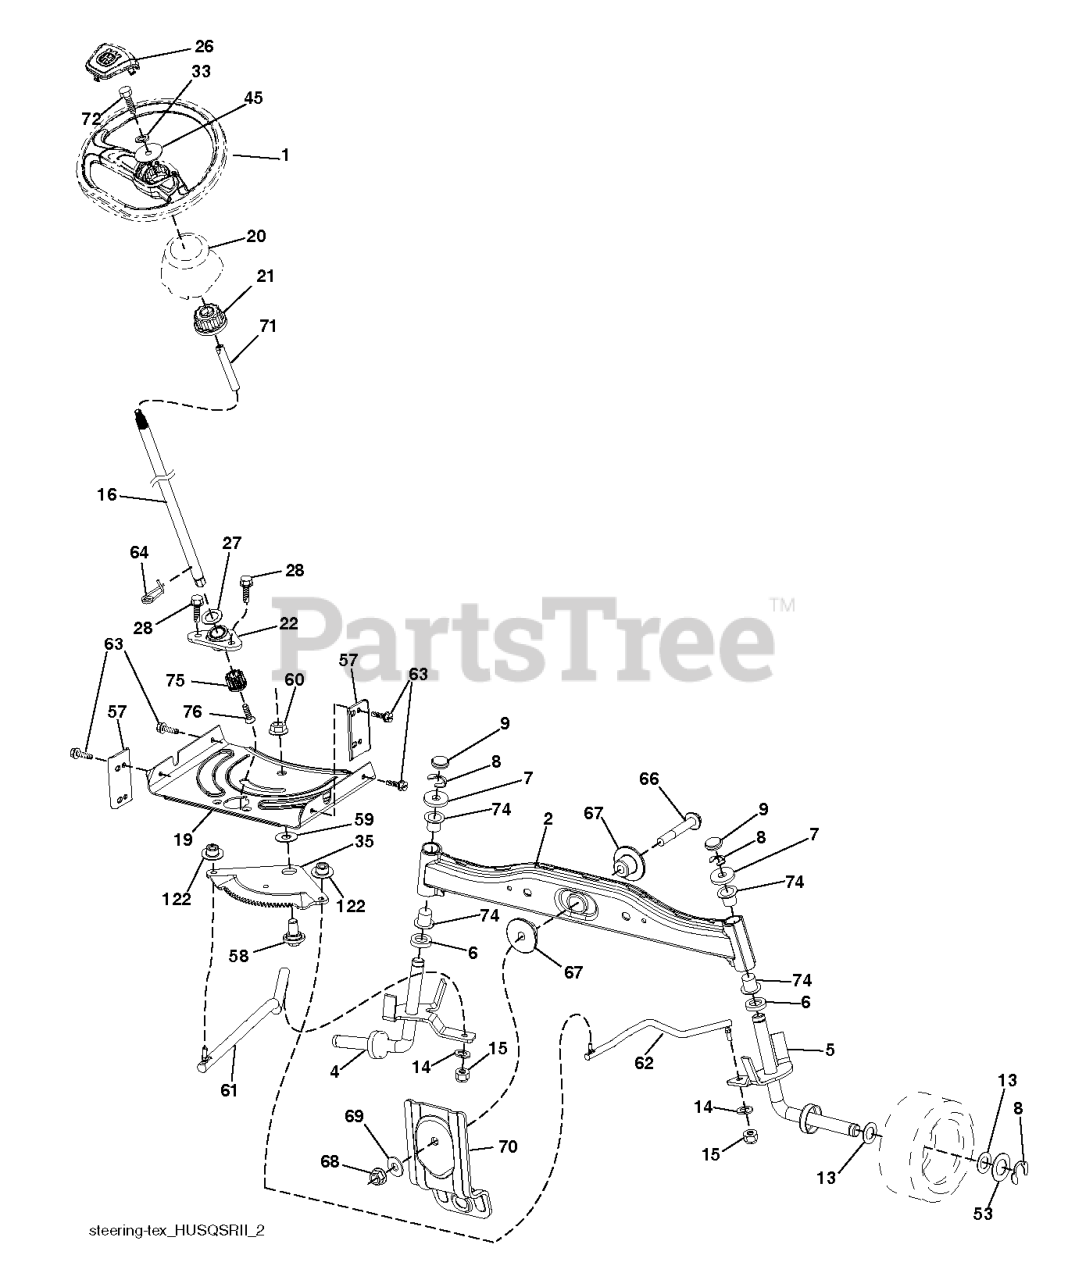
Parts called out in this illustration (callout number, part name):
1	Service Kit
2	AXLE HALF ASM-WELDED
4	SPINDLE.WELDED.LH.15"TEX
5	SPINDLE.WELDED.RH.15"T
6	WASHER THRUST
9	CAP.SPINDLE.BLACK
15	NUT CROWNLOCK 3/8-24
16	3 HIGH.SHAFT-ZINC.PLATED
19	PLATE.STEER.DDL.NLT/NG
20	STEERING.BOOT.HUSQ.LT
21	ADAPTER, WHEEL STNG..
22	BEARING.SHAFT.STEER.LOWER.625
28	SCREW, 3/8-16X3/4
33	WASHER SPRING LOCK WASHER WITH
35	GEAR.SECTOR.PLATE.DDL.
53	WASHER.HARDENED
57	BRACKET.UPSTOP.TEX
58	BOLT.SHOULDER.SECTOR.P
59	WASHER.THURST.SECTOR.S
60	NUT FLANGE LOCK 5/8-11
63	SCREW
64	RETAINER.CLIP.SPRING.S
66	BOLT HEX FGHD 7/16-14 X 3 SERR
67	BUSHING.PM.FRONT AXLE
68	NUT.LOCK.FLANGE.7/16
69	WASHER.1.5X.505X.118
70	BRACKET.FRT.DECK.SUSP.RR.MT431
71	SHAFT.EXTEN.STRG.SPLINE
74	BEARING.STEERING.COLUMN
75	PINION.ZINC PLATED
76	SCREW HEAD SOCKET LRVB
122	CAP.GEAR.SECTOR.TEX
